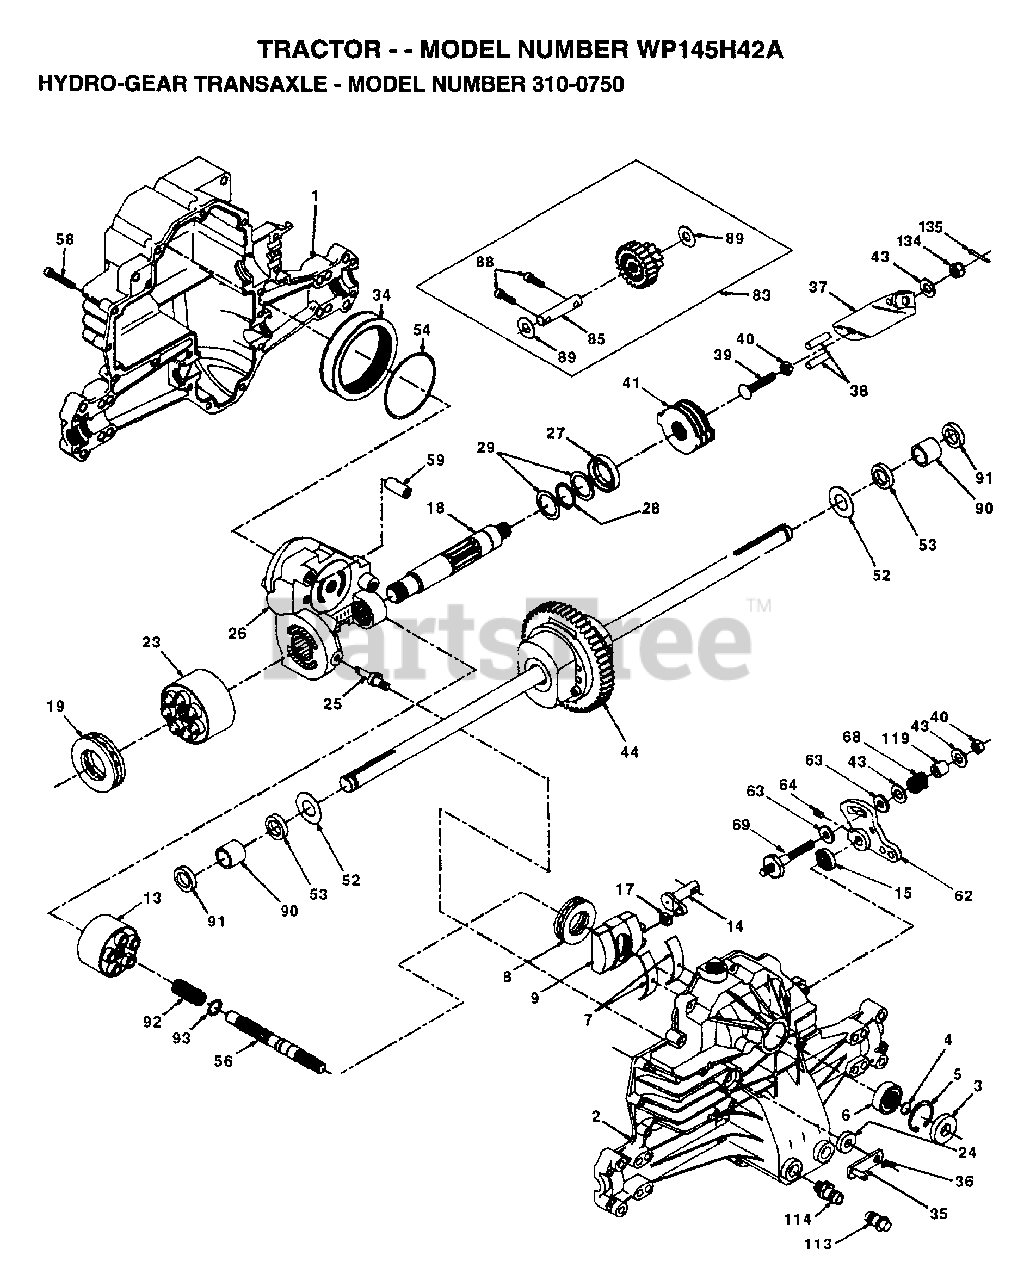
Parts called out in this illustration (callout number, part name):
1	HOUSING.L.50074RM
2	HOUSING.UP.70125
3	SEAL.9008000-0128
4	RING.RET.2003016.
5	RING.RET.2003052.
6	BEARING.(50552)42X68X16
7	CRADLE- 2003023.
8	BEARING.2003044.
9	SWASHPLT.2003087.
13	BLOCK.CLYN.70079.
14	ARM.TRUN.2003005.
15	SEAL.9008000-0126
17	GUIDE.2000015.
18	SHAFT.MOTOR.50115
19	BEARING.THS.50019
23	BLOCK.CYLIN.70082
24	SEAL.LIP.45074
25	ACTUATOR.2003555
26	KIT.CENTER.70133
27	SEAL.LIP.45075
28	RING RETAIN 50007
29	WASHER.44872
34	ELEMENT.OIL.44964
35	ARM.BYPASS.50270
36	RING.RETAIN.44870
37	ARM.ACTUAT.23710
38	PIN.ACTUAT.44891
40	NUT.LOCK.HX.50108
41	KIT.BRAKE.70135
43	WASHER HYD 44130
44	DIFFERENTIA.70130
52	WASHER.HYD.50152
53	SEAL.HYDRO.45076
54	O RING.HYD.45077
56	SHAFT.INPUT.50005
58	BOLT.1/4-20.44876
59	PIN.HYDRO.50002
62	ARM.CONTROL.50254
63	PUCK.DAMPER.50281
64	SCREW.SET.50018.
68	SPRING.HYD.50277
69	STUD.5/16-24.DANA
83	JACKSHAFT/PINION GEAR.70132
85	JACKSHAFT.50086
88	SCREW.CAP.50154.
89	WASHER.HYD.50132
90	BEARING.SLV.50118
91	SEAL.WIPER.50941
92	SPRING.2003014.
93	SPRING.2003014.
93	WASHER.2003017
113	CAP.VENT.70109
114	O-RING.ASM.70110
119	SPACER.HYD.50278
134	NUT.CAS.HYD.44142
135	PIN.COT.HYD.44101
